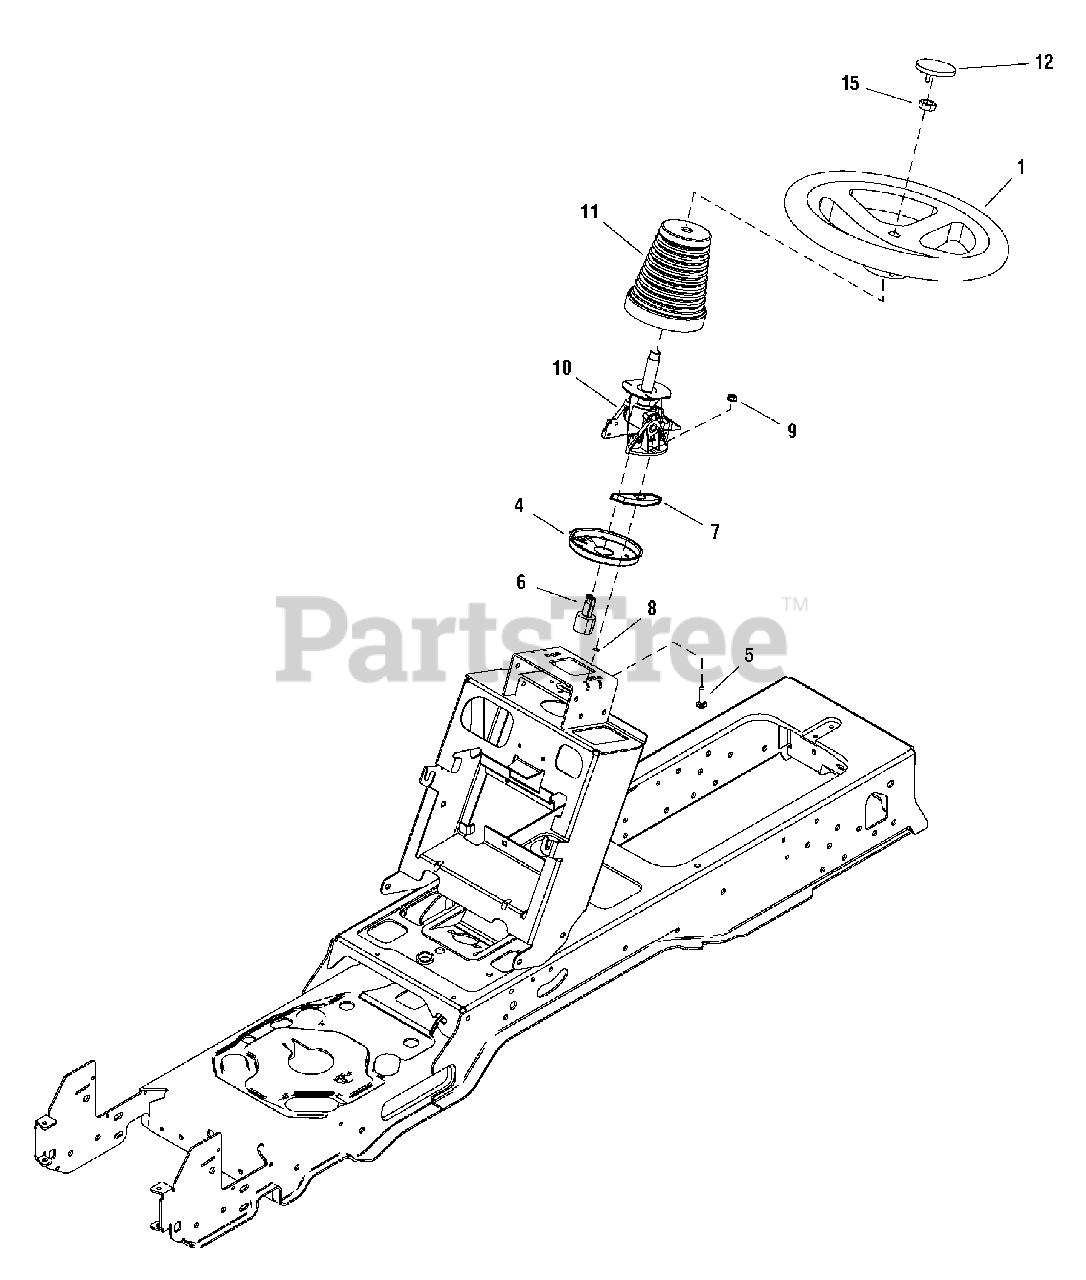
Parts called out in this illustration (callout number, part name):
1	STEERING WHEEL
4	PLATE, Steering Mounting
5	BOLT, Carriage, 5/16-18 x 1-1/4, G5
6	ADAPTER
7	SPACER, Flat
8	NUT, Push Pal
9	NUT, Hex Keps 5/16-18
10	STEERING UNIT, Tilt
11	BELLOWS, Tilt Steering Unit w/Slot
12	CAP, Steering Wheel
15	NUT, Hex Lock ESNA Light 5/8-18
